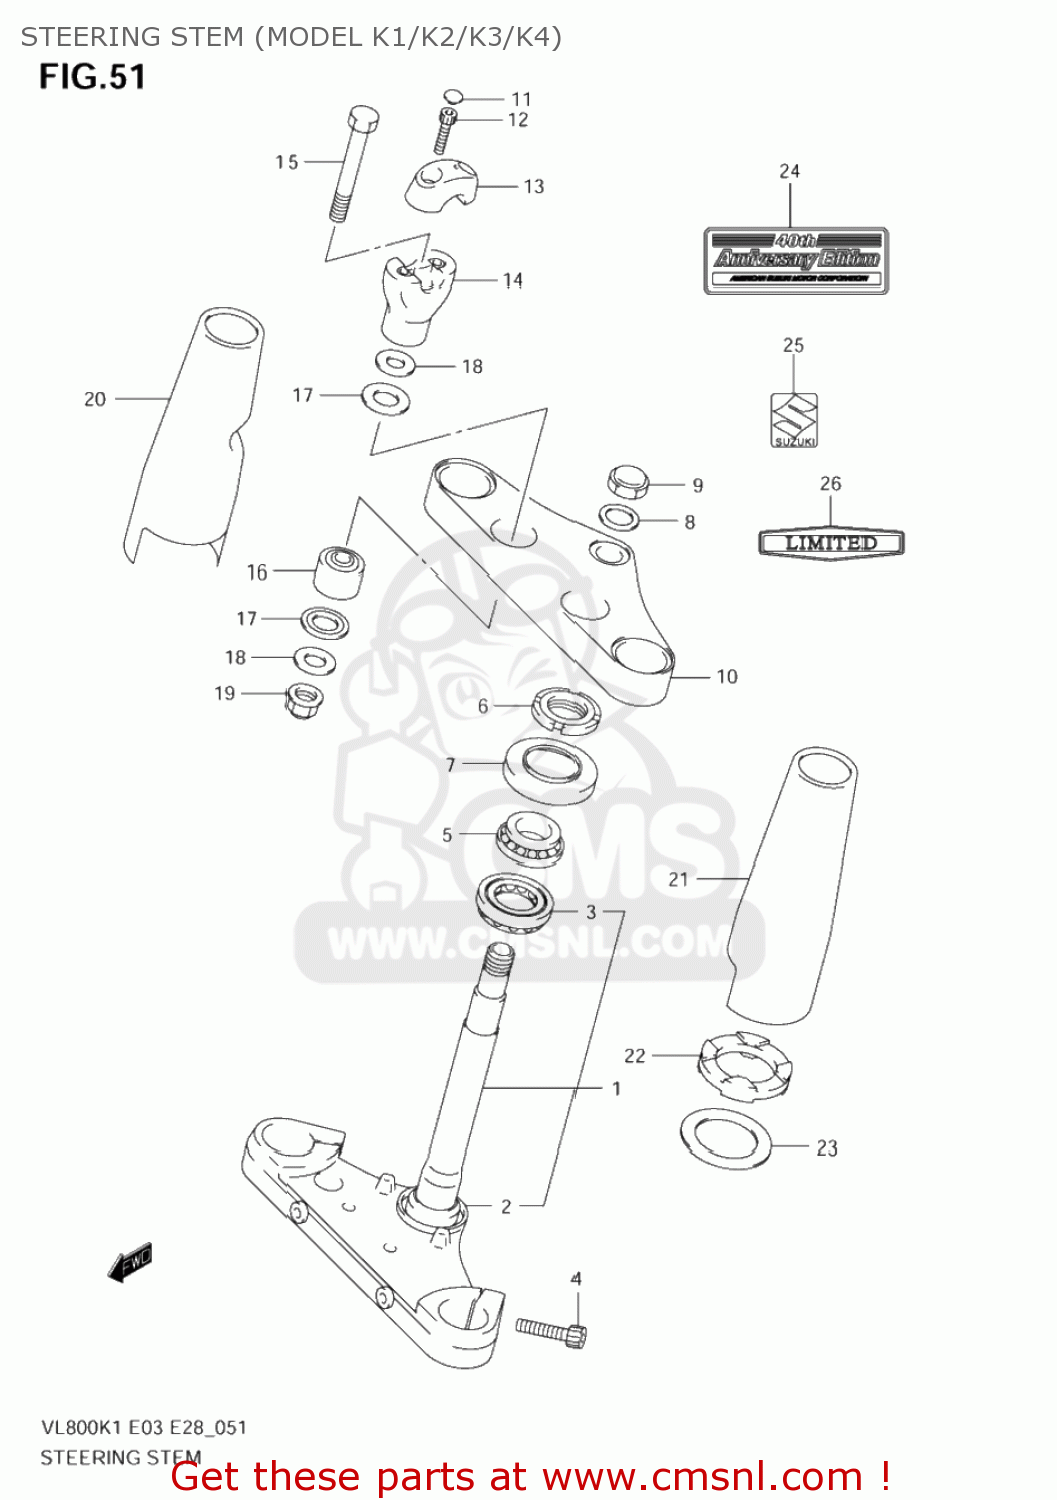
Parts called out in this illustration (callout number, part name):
1	STEM,STEERING
2	SEAL,STEERING LWR
3	BEARING(30X55X17)
4	BOLT
5	BEARING(25X47X15)
6	NUT,STEERING STEM(25X44X10)
7	DUST SEAL,STEERING UPR
8	WASHER(22.5X32X1.6)
9	NUT,CAP
10	HEAD,STEERING STEM
11	CAP(OD:14.5)
12	BOLT
13	HOLDER,HANDLE UPR
14	HOLDER,HANDLE UNDER
15	BOLT
16	DAMPER,RUBBER
17	SEAT,RUBBER
18	WASHER
19	NUT
20	COVER,UPR,R
21	COVER,UPR,L
22	SEAT,RUBBER
23	WASHER
24	EMBLEM,40TH
25	EMBLEM,S
26	EMBLEM,LIMITED
